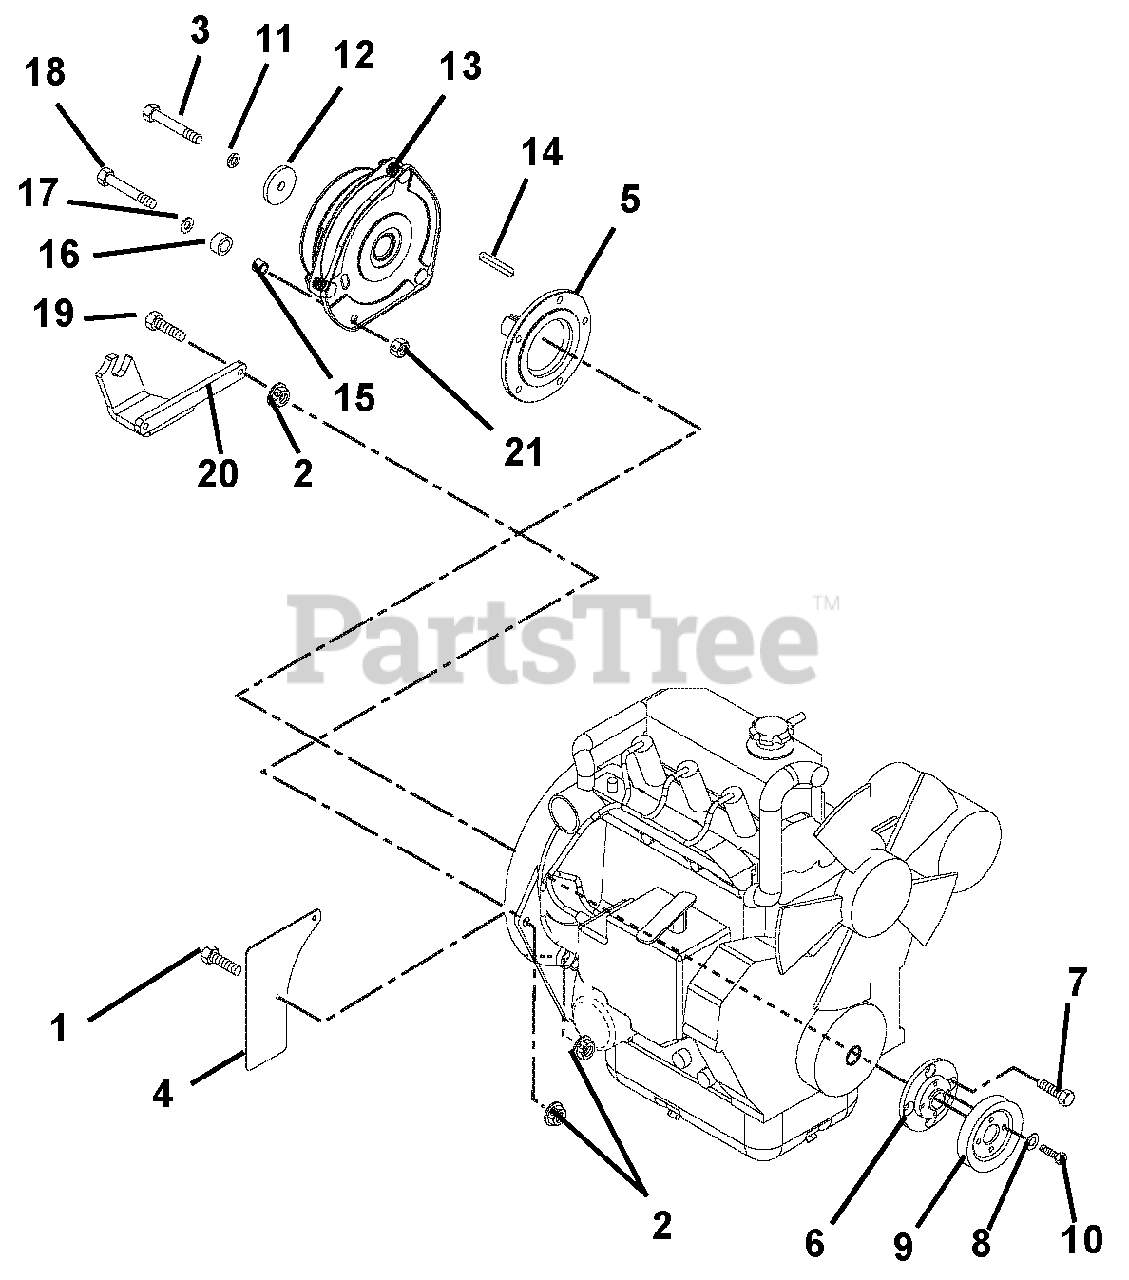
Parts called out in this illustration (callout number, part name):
1	Bolt, Hex .31 -18 x .75 Grade 5
2	Nut, Locking Top Flange .31-18
3	Bolt, Hex .44-20 x 2.50 Grade 5 YZ EP80
4	Guard, Flywheel
5	Stub Shaft
6	Adapter, Sheave
7	Bolt, M8 1.25 x 25
8	Washer, Locking .25 x .062
9	Sheave, Poly V 1.0 x 3.25
10	Bolt, Hex .25-20 x .75 Grade 5
11	Washer, Locking .44 x .109 Regular
12	Washer, Flat Steel .469 x 2.00 x .25
13	Clutch, Ogura
14	Key .25 x .25 x 2.25
15	Spacer .375 x .688 x .500
16	Bumper, Rubber .62 x 1.0 x .51
17	Washer, Flat Steel .406 x .812 x .065
18	Bolt, Hex .38-16 x 1.00 Grade 5
19	Bolt, Hex .31-18 x 1.25 Grade 5
20	Bracket, Clutch Stop
21	Nut, Hex Jam .375-16
